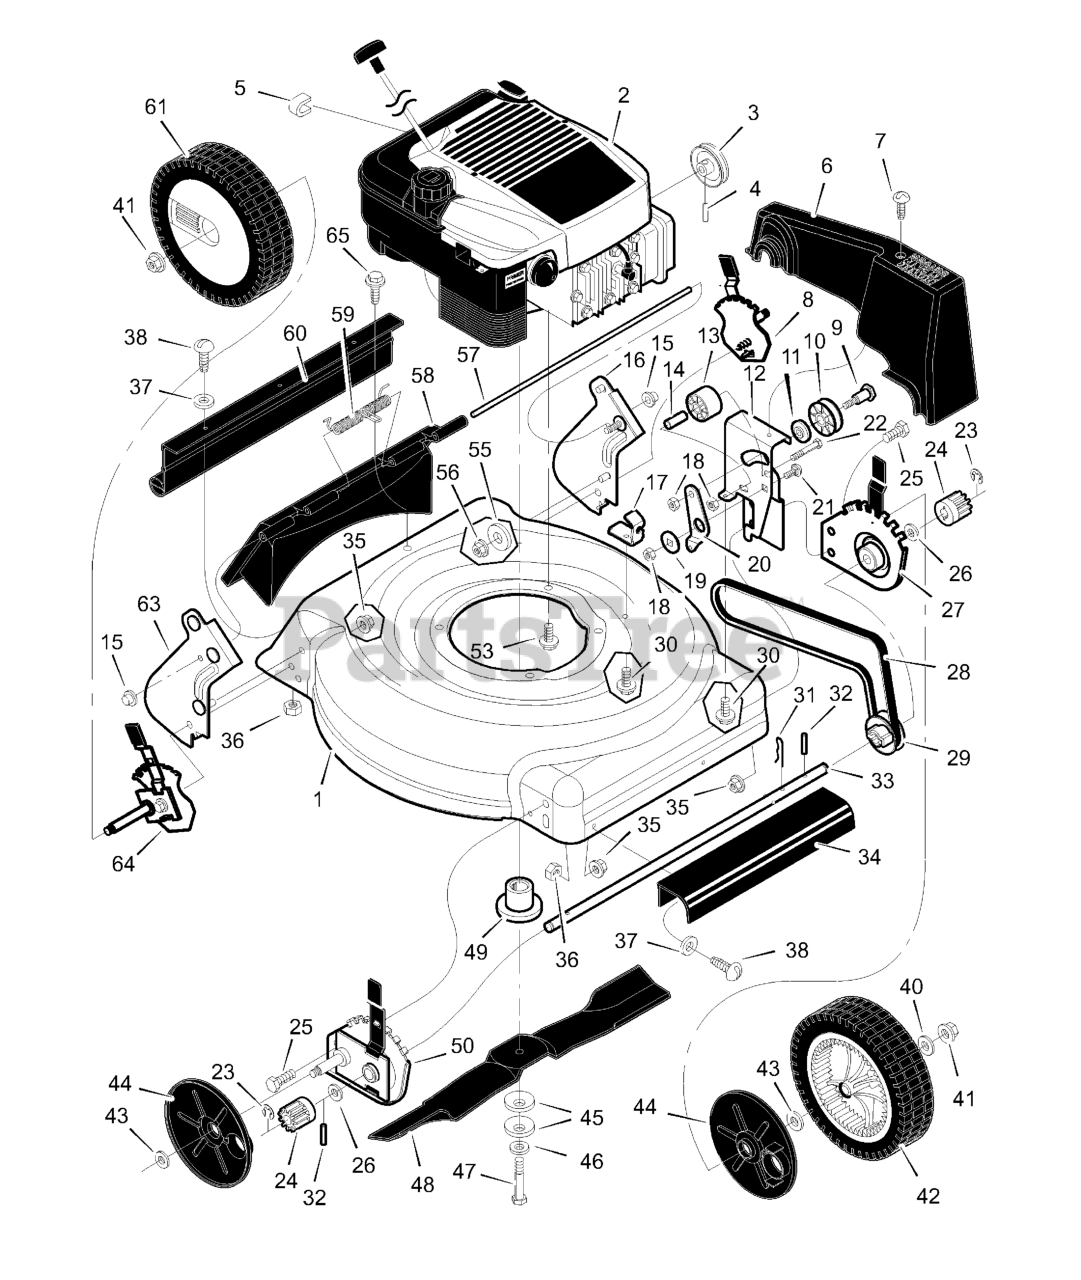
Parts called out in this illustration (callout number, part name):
1	Housing
2	Engine *
3	Pulley, Engine
4	Pin, Spring
6	Cover, Belt (Black)
8	Adjuster, Left Height
9	Bolt, Shoulder
12	Bracket, Idler Support
13	Pulley, Idler
14	Bearing
15	Nut, Push
16	Bracket, Left Handle
17	Bracket, Cable
18	Nut, Hex
20	Arm, Idler
21	Bolt, Carriage
22	Bolt, Shoulder
24	Gear, Pinion
25	Bolt
27	Adjuster, Left Frt. Height
29	Pulley, Axle
31	Pin, Hair
32	Pin, Spring
34	Cover, Axle (Black)
35	Nut, Flange
36	Nut, Hex
40	Washer
41	Nut, Flange
42	Wheel, Drive
44	Cover, Dust
45	Washer, Belleville
49	Adapter, Blade
50	Adjuster, Right Frt. Height
53	Bolt, Engine
55	Washer
56	Nut, Flange
57	Rod, Pivot
58	Door, Rear (Black)
60	Deflector, Rear
61	Wheel, Rear
63	Bracket, Right Handle
64	Adjuster, Right Height
